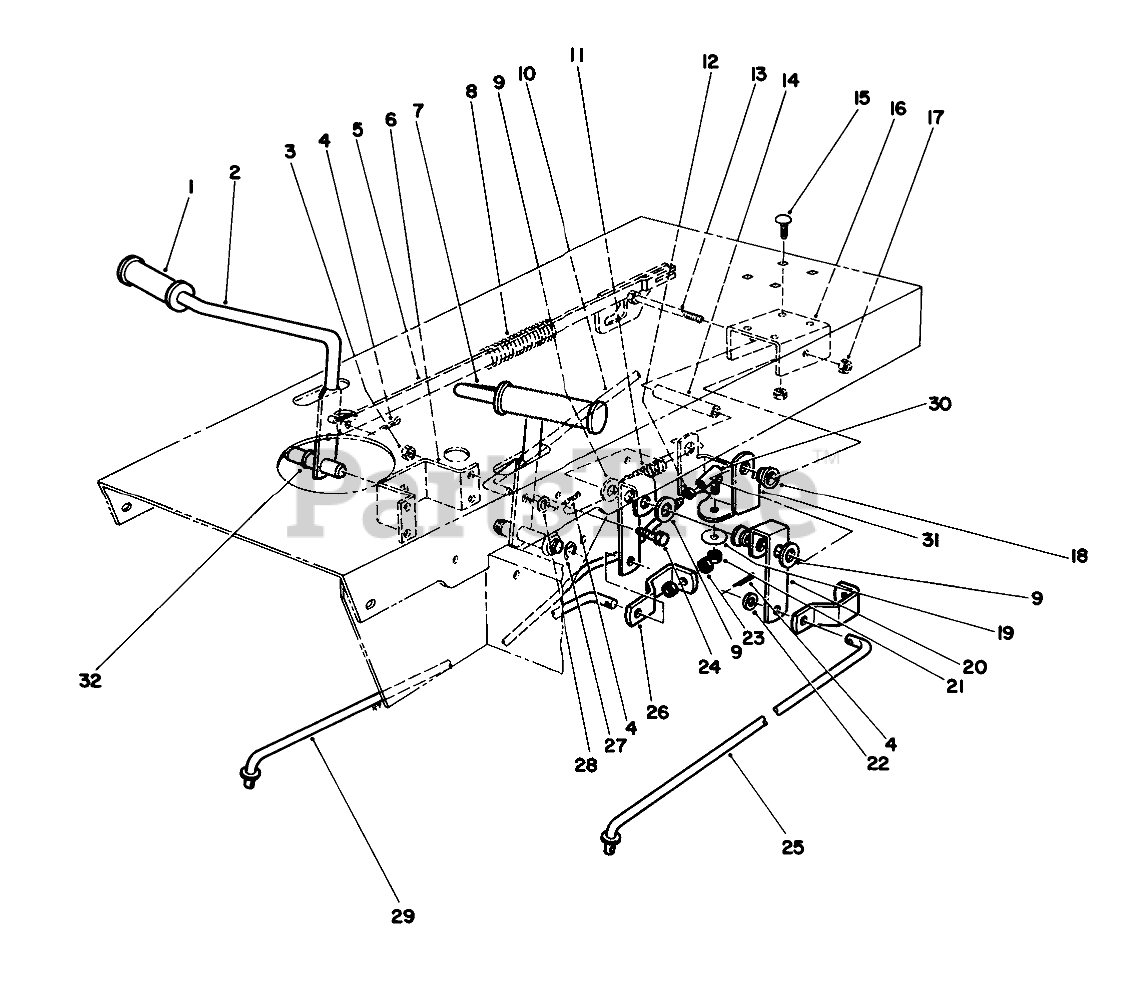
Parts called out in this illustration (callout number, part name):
1	FOOT PAD
2	BRAKE PEDAL WA B
3	NUT-LOCK, NI
4	PIN-COTTER
5	BRAKE LINK WA B
6	FOOT PEDAL BRACKET
7	CLUTCH PEDAL WA B
8	EXTENSION SPRING
9	WASHER-FLAT
10	CLUTCH ROD
11	SPRING-EXTENSION
12	NUT-JAM
13	SCREW-HH
14	CLUTCH BRACKET SLEEVE
15	SCREW-CARR
16	CLUTCH SUPPORT BRKT B
17	NUT-LOCK, NI
18	BUSHING
19	WASHER-PIVOT
20	STEERING LEVER
21	NUT-LOCK, NI
22	WASHER-PLAIN
23	NUT-JAM
24	SCREW-HH
25	LEFT FRONT ROD
26	PULL ROD LINK
27	E-RING
28	WASHER-FLAT
29	RIGHT FRONT ROD
30	BALLJOINT-RH (W/GROMMET)
31	CLUTCH BRACKET
32	Nyliner
